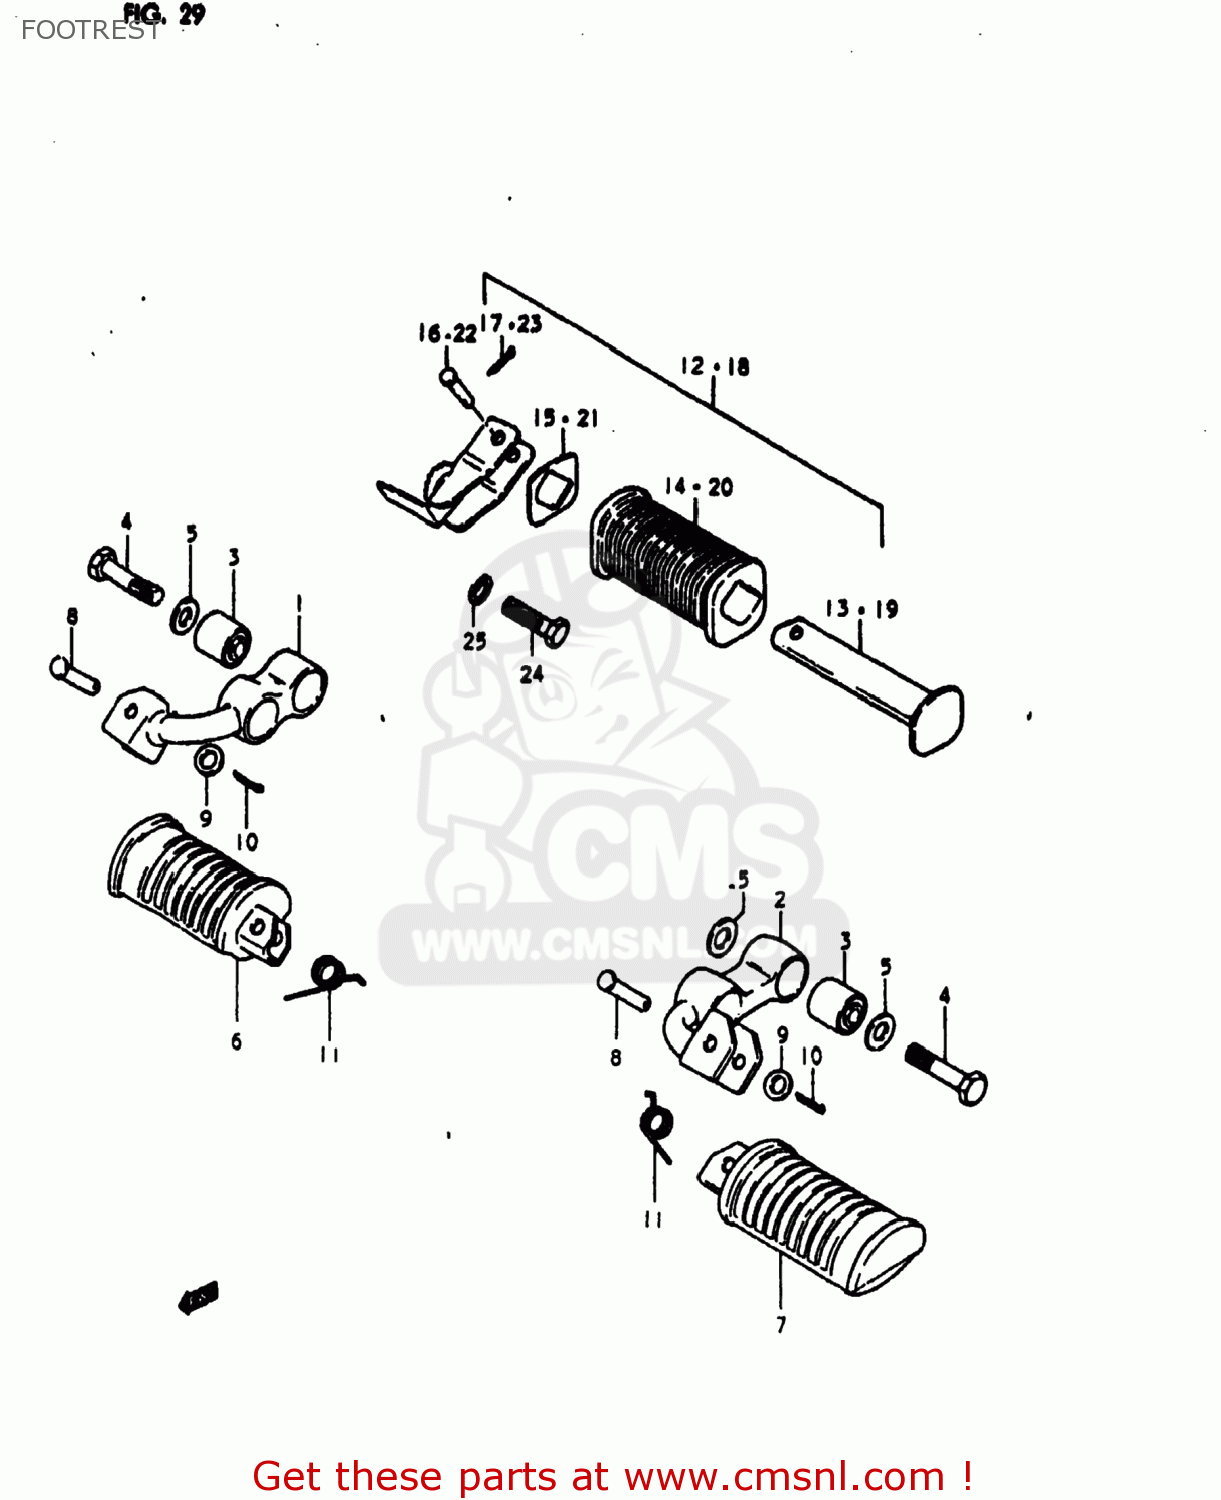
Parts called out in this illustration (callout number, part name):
1	BAR,FRONT FOOTREST
2	BAR,FRONT FOOTREST,LEFT
3	BUSH
4	BOLT
5	WASHER (10.1X21X2.3)
6	RUBBER,FRONT FOOTREST
7	FOOTREST
8	PIN
9	WASHER
10	PIN
11	SPRING
12	FOOTREST ASSEMBLY,REAR
13	BAR,REAR FOOTREST
14	RUBBER,PILLION FOOTREST
15	WASHER,REAR FOOTREST RUBBER
16	PIN
17	PIN
18	FOOTREST ASSEMBLY,PILLION
19	BAR,REAR FOOTREST
20	RUBBER, LH
21	WASHER,REAR FOOTREST RUBBER
22	PIN
23	PIN
24	BOLT 10X30
25	LOCK WASHER
